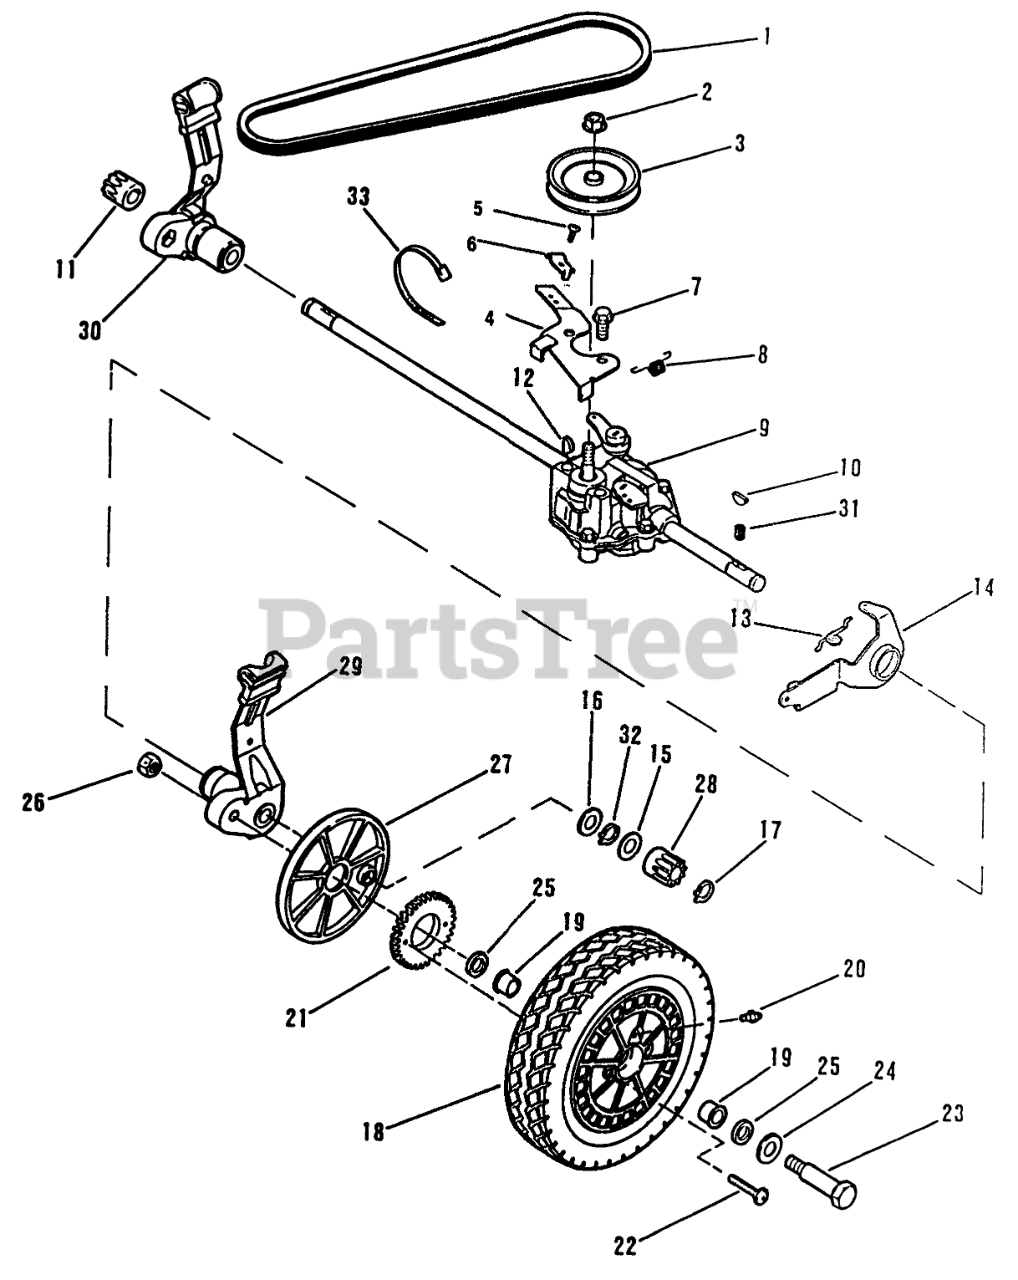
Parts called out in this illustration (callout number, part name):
1	V BELT SM
2	NUT-LOCK
3	PULLEY TRANS ADAMS
4	LINKAGE PLATE&SCRW
5	SCREW-CLAMP SM
6	CLAMP-CABLE
7	SCREW SELF TAP
8	SPRING-EXTENSION
9	TRANSMISSION ASSEM
10	KEY
11	PINION(R)MET ALLEG
12	KEY GALGER
13	LINK
14	Actuator Arm and Bushing
15	THRUST WASHER
16	WASHER-THRUST
17	RETAINING RING
18	Wheel, Tire and Brg Assy
19	BEARING
20	FITTING LINCOLN
21	GEAR
22	SCREW-TORX
23	BOLT WHEEL QUAL
24	WASHER-PLAIN
25	WASHER
26	NUT
27	W/COVER WHITE PL
28	PINION(L)MET ALLEG
29	HT. ADJ. ARM AY-L
30	HT. ADJ. ARM AY-R
31	SPRING
32	RET RING
33	TIE STRAP
